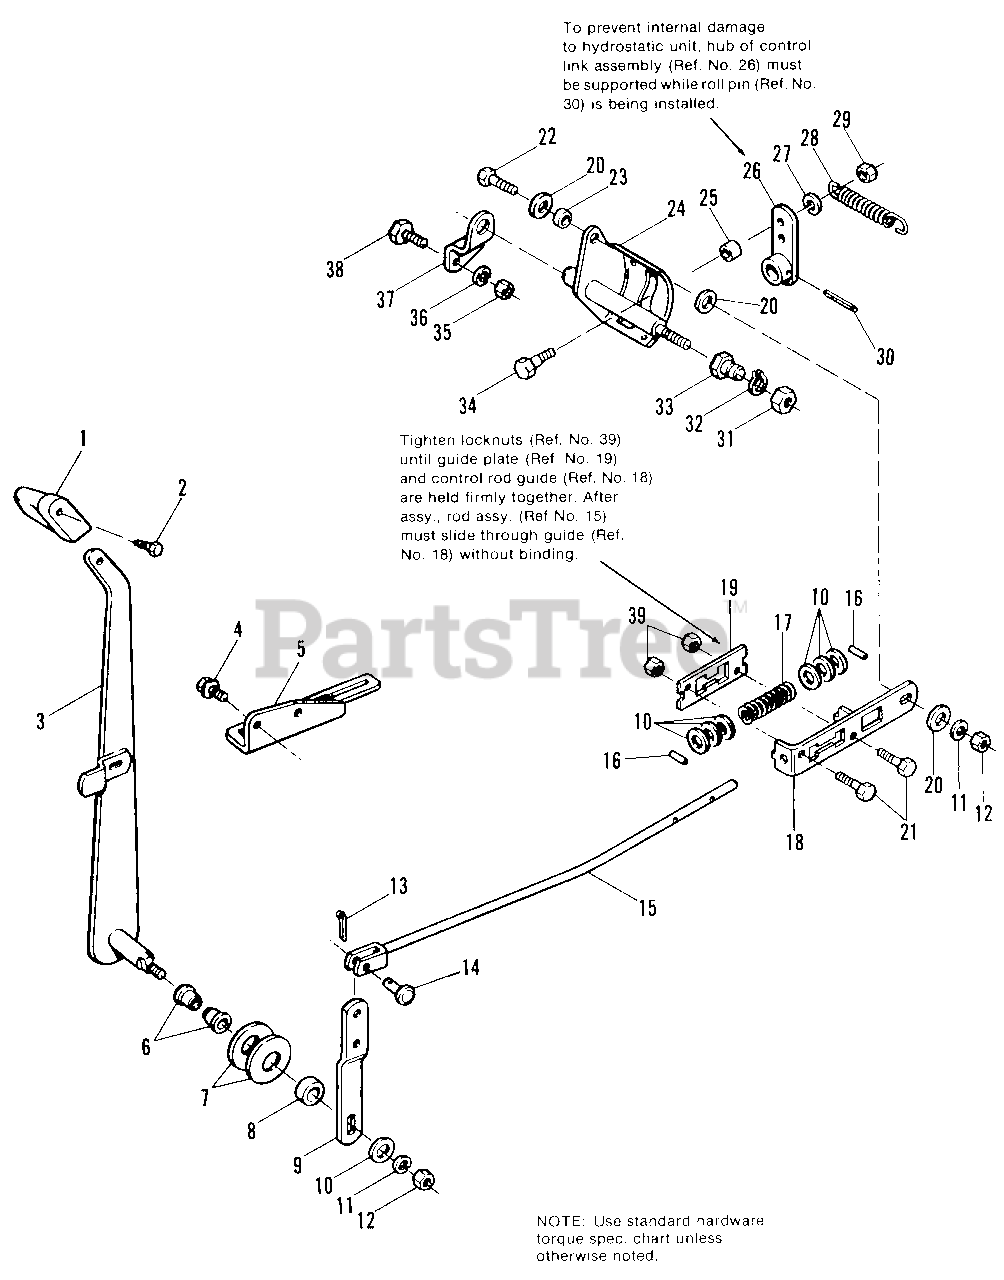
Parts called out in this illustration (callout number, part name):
2	SCREW, Thd. Form., 1/4-20 x 3/4
3	LEVER ASSY., Control
4	SCREW, Hex, Flange, Whizlock, 5/16-18 x 1/2
5	QUADRANT
7	WASHER, Spring
10	WASHER, 3/8
11	LOCKWASHER, 3/8
12	NUT, Hex, Full, 3/8-16
13	PIN, Cotter, 3/32 x 3/4
15	ROD ASSY., Control
18	GUIDE, Control Rod
19	PLATE, Guide
20	WASHER, 5/16
21	CAPSCREW, Hex Hd., 1/4-20 x 1-1/4
22	CAPSCREW, Hex Hd., 3/8-16 x 1
24	SHAFT ASSY.
25	ROLLER, Cam
26	LINK ASSY., Control
27	LOCKWASHER, 1/4
29	NUT, Hex, Full, 1/4-20
30	PIN, Roll, 1/4 x 1-1/4
31	NUT, Hex, Jam, 1/2-13
32	RING, Retaining
33	NUT, Adjusting
34	BOLT, Shoulder
35	NUT, Hex, Full, 5/16-18
36	LOCKWASHER, 5/16
37	BRACKET, Pivot
38	SCREW, Special
39	LOCKNUT, Hex, 1/4-20
